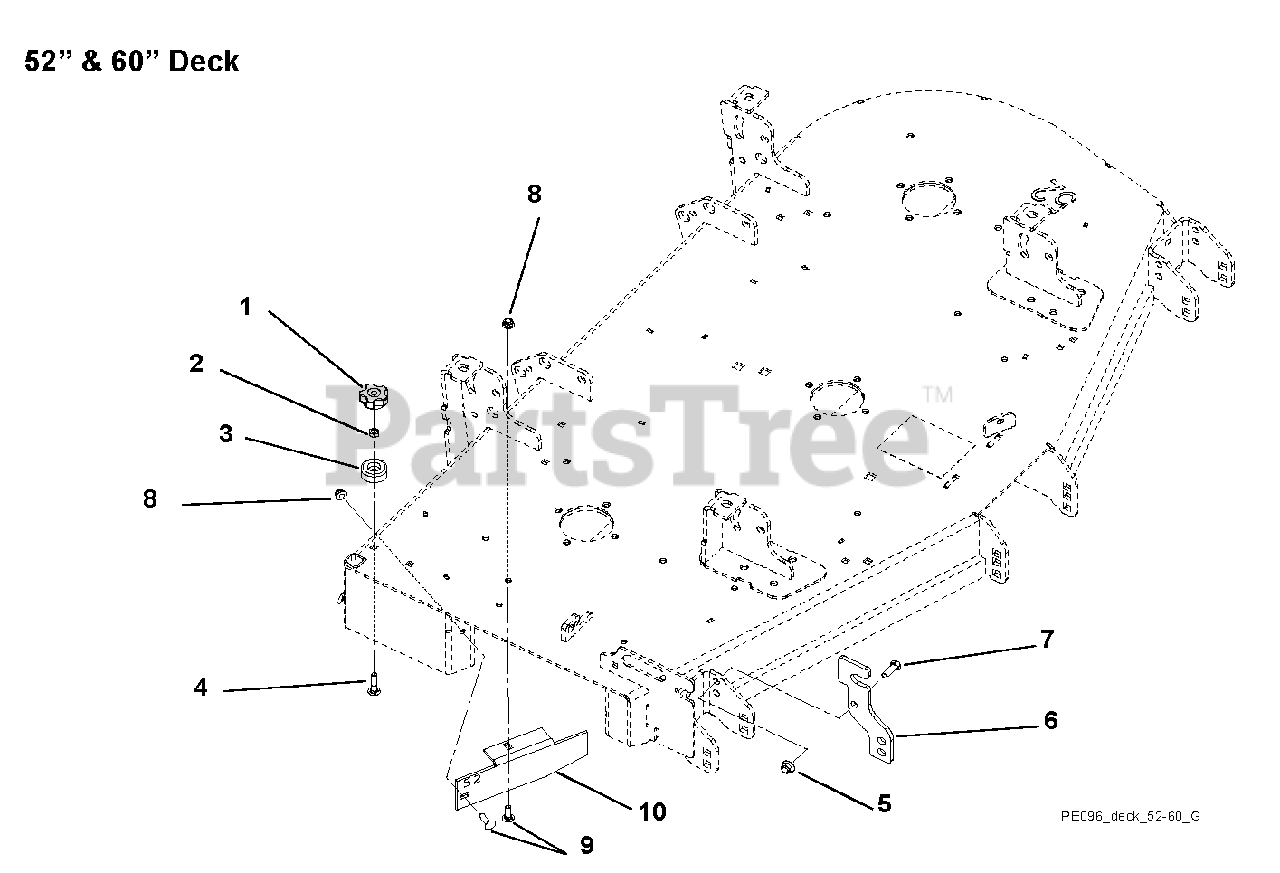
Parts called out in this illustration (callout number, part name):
1	Knob, Clamping, .312-18 Nyloc
2	Nut, Locking Center .31-18
3	Bumper, Recessed 1.50 x .63 w/.31 Thru Hole
4	Bolt, Round Head Square Neck .31-18 x 1.50
5	Nut, .38-16 Nyloc Flange
6	Chute Storage Bracket
7	Bolt, Hex .38-16 x 1.00
8	Nut, Locking Nyloc Flange .31-18
9	Bolt, Round Head Square Neck .31-18 x 1.00
10	Discharge Baffle (991080, 096, 103)
